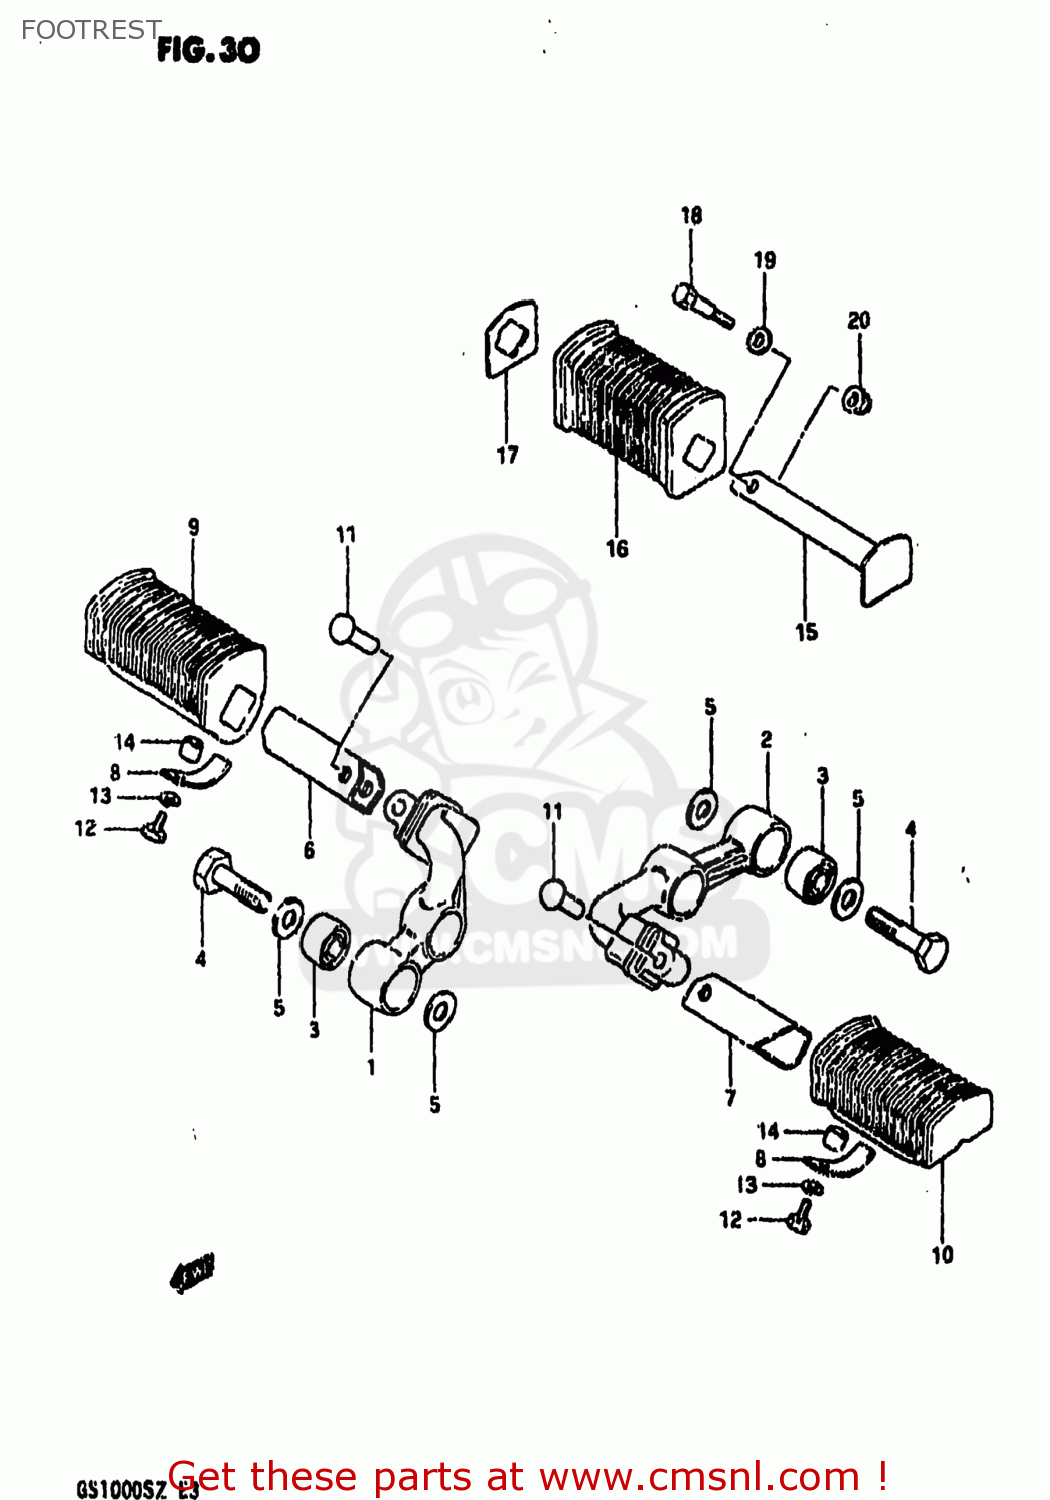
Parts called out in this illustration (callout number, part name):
1	BAR, FOOTREST RH
2	BAR, FOOTREST LH
3	BUSH
4	BOLT
5	WASHER
6	HOLDER, COVER RH
7	HOLDER, COVER LH
8	PLATE, FOOTREST STOPPER
9	RUBBER,FR FOOTREST,R
10	RUBBER,FR FOOTREST,L
11	RIVET
12	BOLT, UPPER
13	LOCK WASHER
14	SPACER(6.5X10.5X6.5)
15	BAR, RH
16	RUBBER,PILLION FOOTREST
17	WASHER,PILLION FOOTREST RUBBER
18	BOLT(6X40)
19	WASHER
20	NUT
